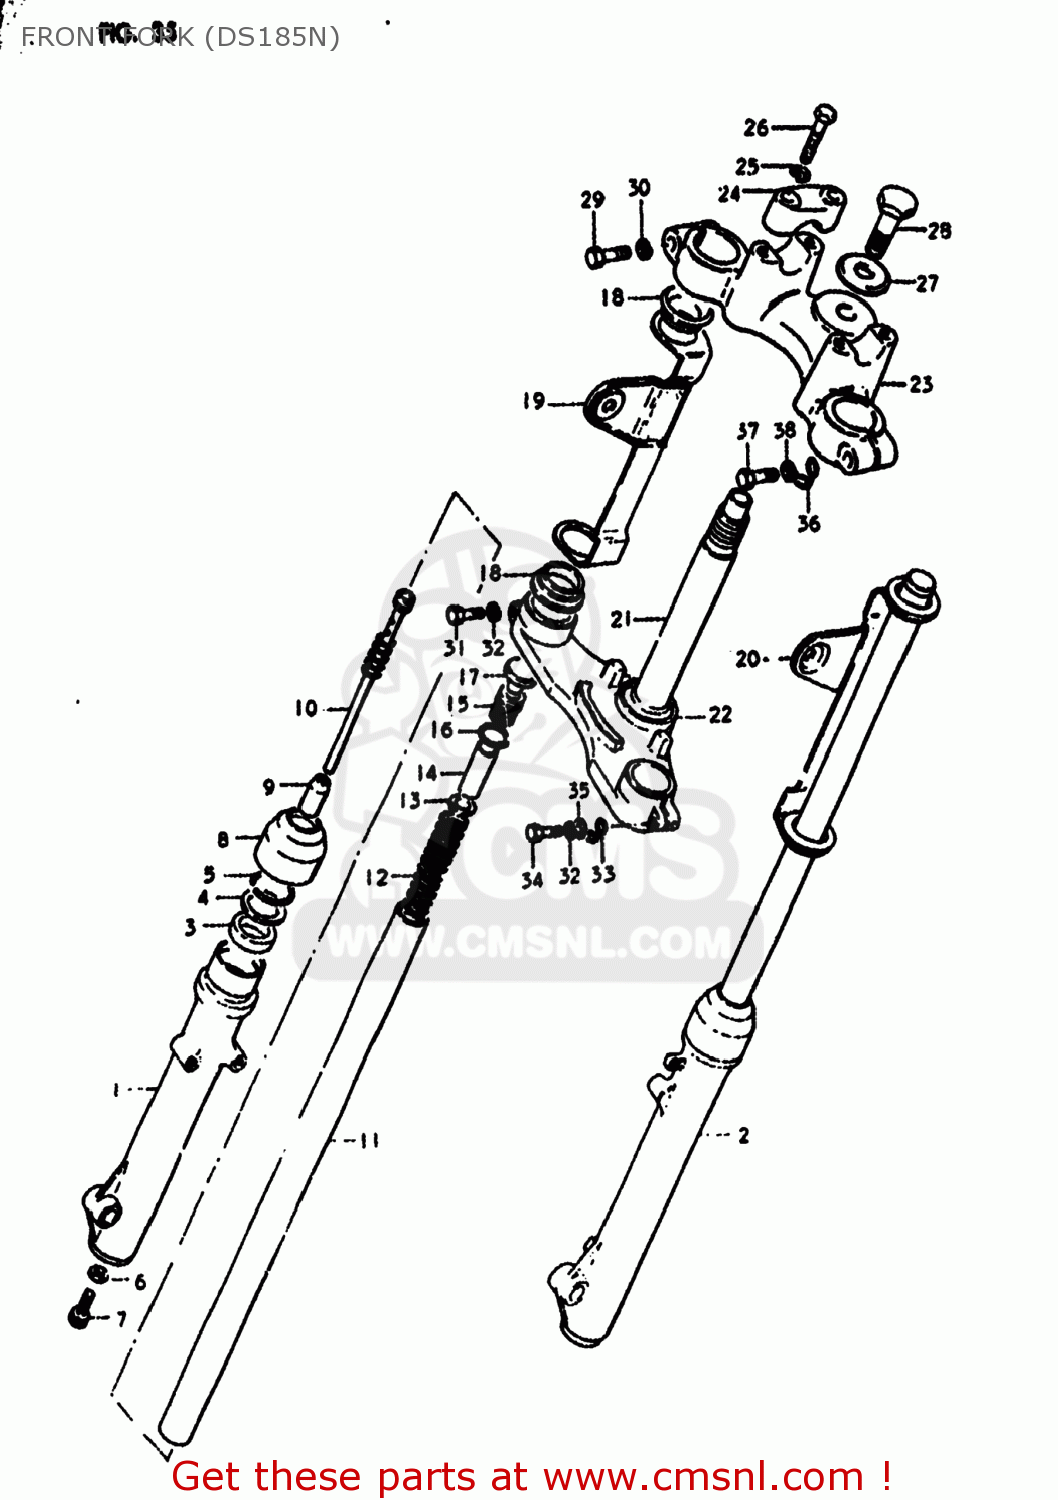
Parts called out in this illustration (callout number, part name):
1	TUBE,FORK,OUTER,RIGHT
2	TUBE,OUTER,LEFT
3	OIL SEAL,FRONT FORK
4	WASHER
5	RING,SNAP
6	GASKET (NAS)
7	BOLT,FORK CYLINDER(10X25)
8	SEAL,DUST
9	PIECE,OIL LOCK
10	CYLINDER,FRONT FORK
11	TUBE,FORK,INNER
12	SPRING
13	GUIDE,SPRING COVER
14	SPACER,SPRING
15	CAP
16	O-RING,FORK INNER TUBE
17	CAP,FRONT FORK
18	CUSHION,HEADLAMP BRACKET
19	BRACKET,HEADLAMP HOUSING
20	BRACKET,HEADLAMP,LEFT
21	STEM,STEERING
22	RACE,STEERING OUTER LWR
23	HEAD,STEERING STEM
24	HOLDER,HANDLE(BLACK)
25	LOCK WASHER
26	BOLT
27	WASHER,STEM HEAD(10.5X30X3.2)
28	BOLT,FORK INNER TUBE
29	BOLT,FORK INNER TUBE F
30	LOCK WASHER
31	BOLT
32	WASHER,LOCK 12
33	CLIP
34	BOLT 12X45
35	WASHER
36	CLIP
37	BOLT 10X40
38	WASHER
